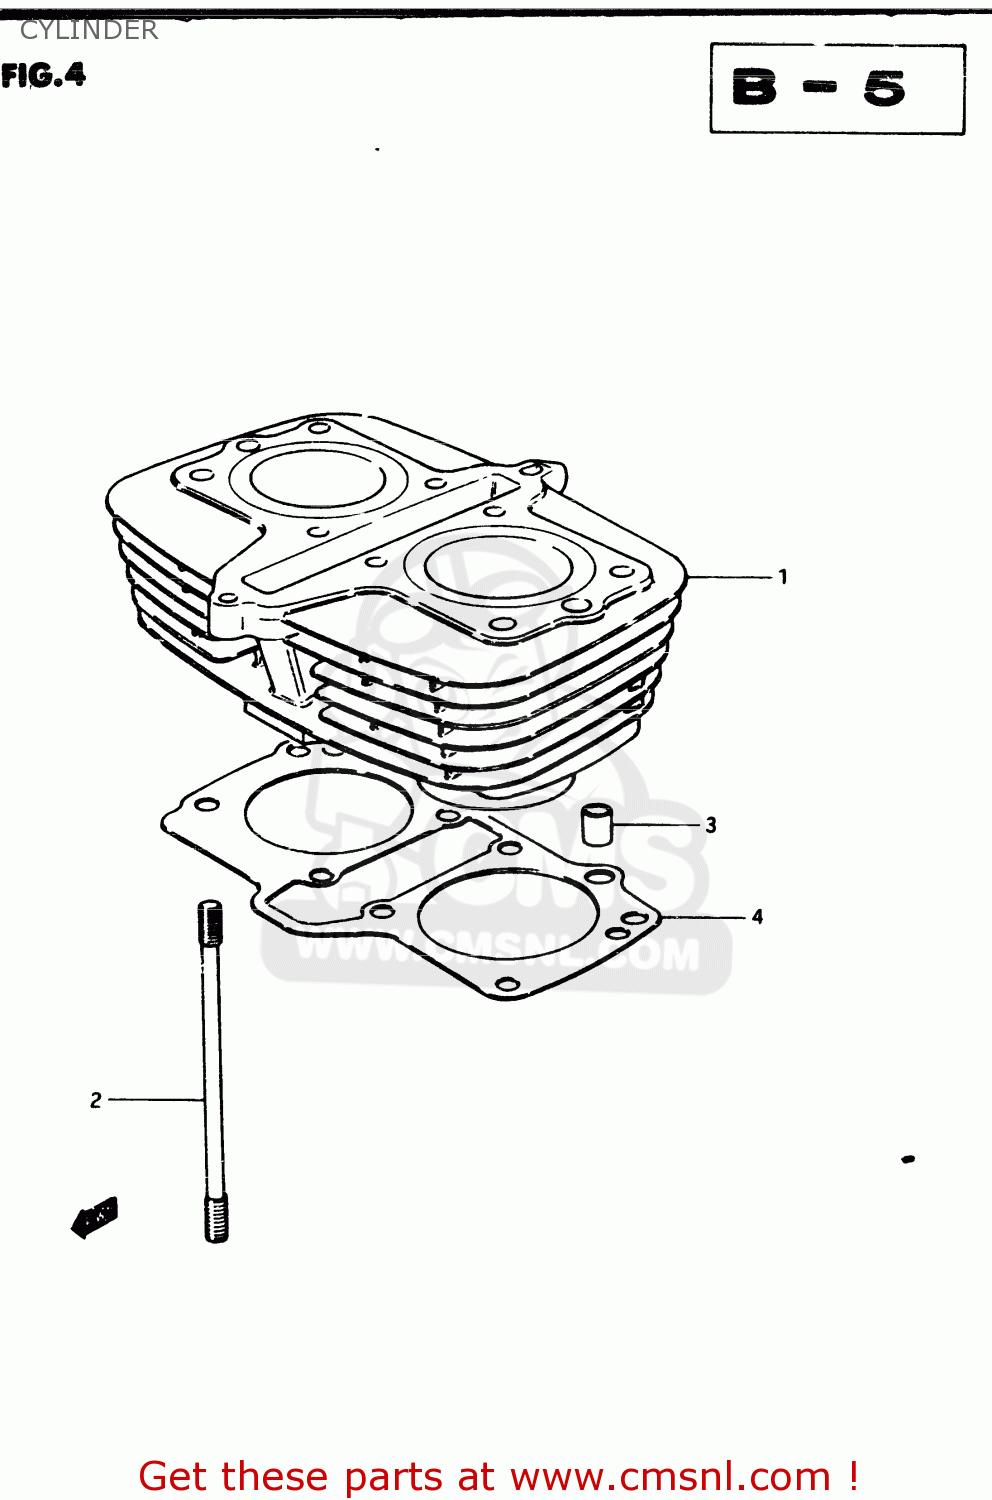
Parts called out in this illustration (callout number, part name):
1	CYLINDER
2	STUD
3	PIN
4	GASKET (T:1.0) (MCA)
